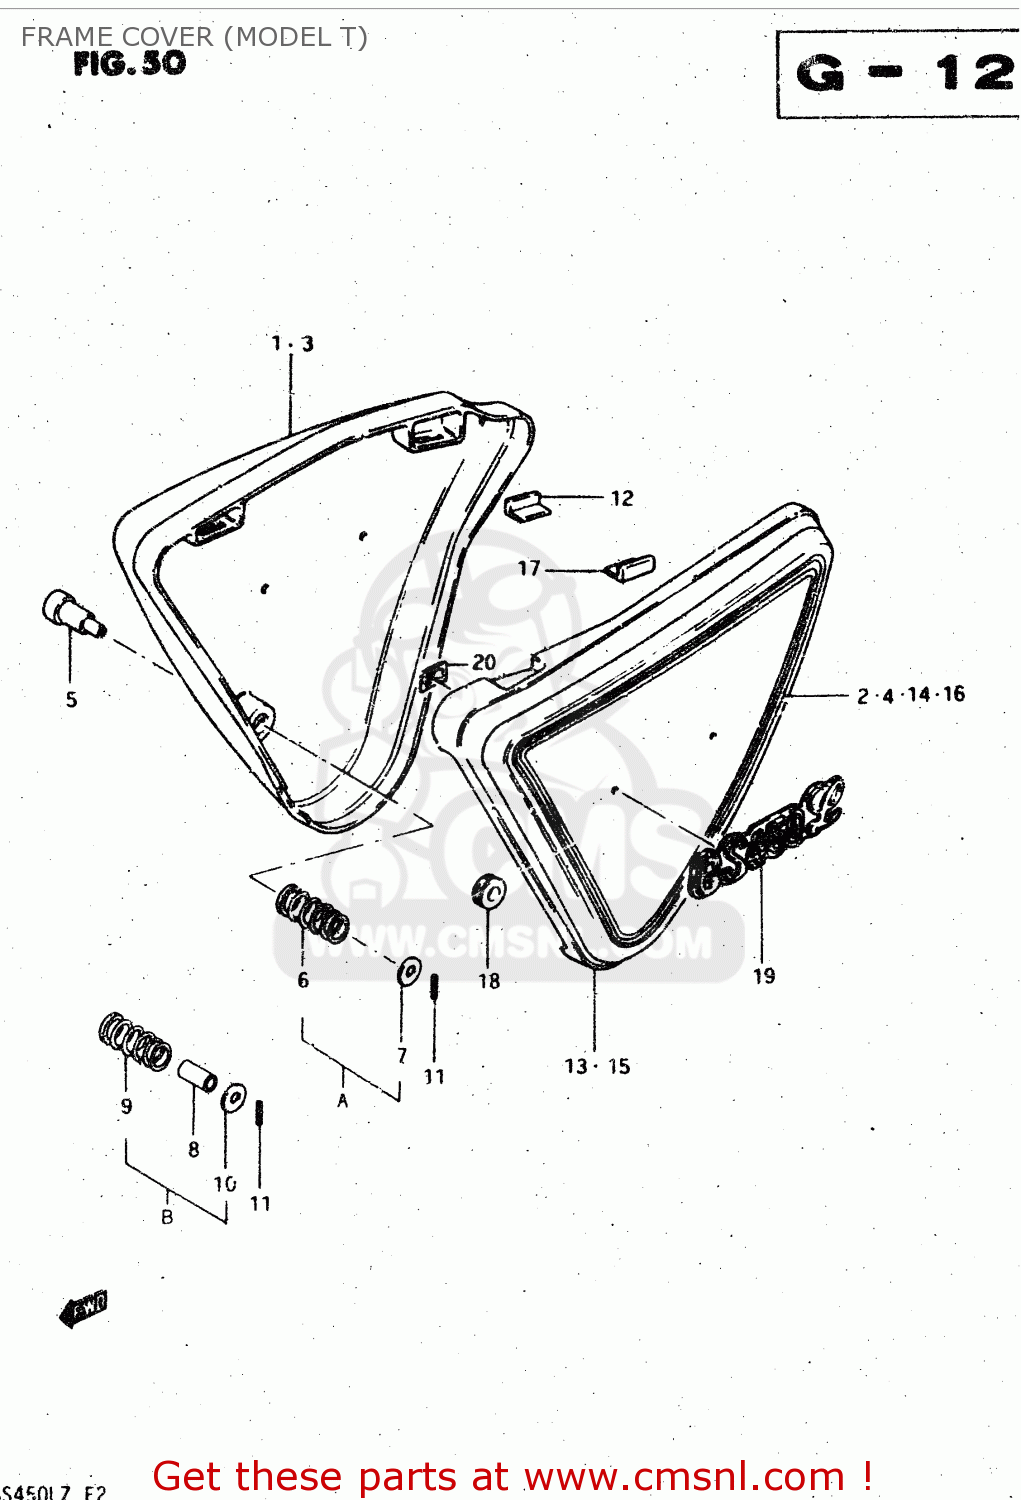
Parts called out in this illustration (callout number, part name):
1	COVER,FRAME,RIGHT
2	TAPE SET,FRAME COVER
3	COVER,FRAME,RIGHT
4	TAPE SET,FRAME COVER,RIGHT
5	KNOB,FRAME COVER,R
6	SPRING
7	WASHER
8	SPACER(14.9X17.3X13.5)
9	SPRING
10	WASHER (6.5X24X1.6)
11	PIN,SPRING(2.5X18)
12	CUSHION,FRAME COVER
13	COVER,FRAME,LEFT
14	TAPE SET,FRAME COVER
15	COVER,FRAME,LEFT
16	TAPE SET,FRAME COVER,LEFT
17	CUSHION,FRAME COVER
18	CUSHION
19	EMBLEM
20	NUT
